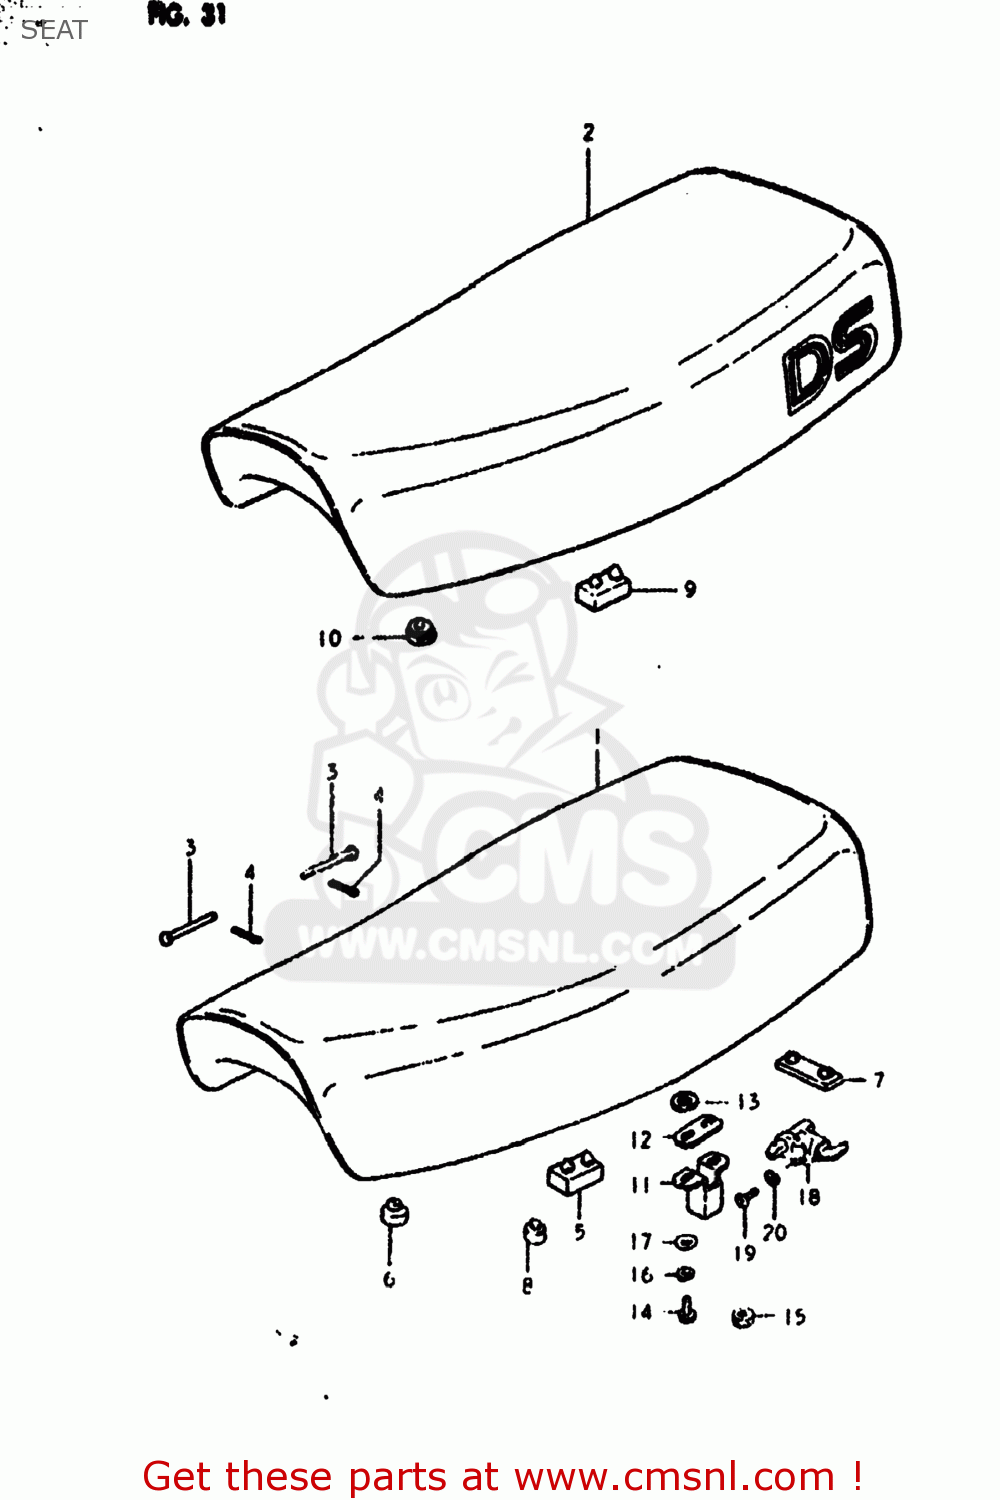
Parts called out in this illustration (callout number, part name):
1	SEAT ASSEMBLY
2	SEAT ASSEMBLY
3	PIN
4	PIN
5	CUSHION
6	CUSHION(11.5X22X20)
7	CUSHION
8	CUSHION
9	CUSHION
10	CUSHION
11	PLATE,CLAMP GUIDE
12	SHIM,SEAT LOCK STRIKER
13	WASHER(8.5X18X1)
14	BOLT
15	NUT
16	LOCK WASHER
17	WASHER
18	LOCK ASSEMBLY,SEAT
19	SCREW
20	LOCK WASHER
